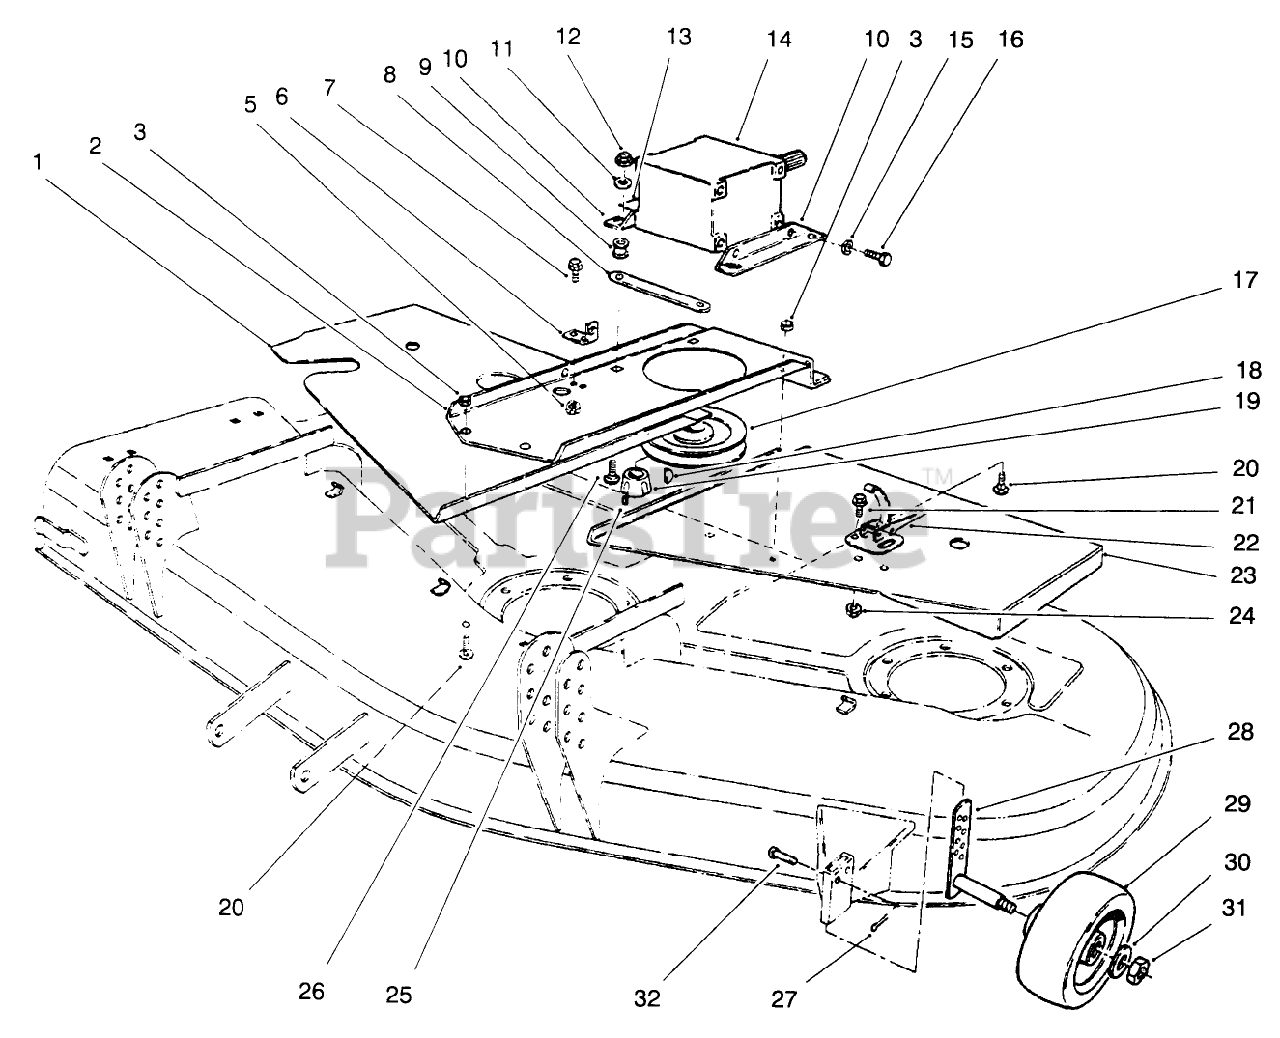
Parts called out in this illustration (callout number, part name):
1	Cover RH
2	Base-Gear Box
3	NUT-HHF, WHIZ
5	NUT-HF
6	Bracket-Extension
7	SCREW-HH
8	Cover-Gear Box
9	MOUNT
10	Bracket-Gearbox
11	WASHER
12	NUT-LOCK, SIDE
13	DECAL-OIL
14	Gearbox
15	WASHER-LOCK
16	SCREW-HH
17	PULLEY
18	KEY-WOODRUFF
19	Bushing-Taper Lock (Incl. Ref. #25)
20	SCREW-CARR
21	SCREW-HWH
22	CLAMP-SLOTTED
23	Cover LH
24	NUT-LOCK, FLANGE
25	SCREW-SET, HSH
26	SCREW-CARR
27	PIN-HAIR
28	GAGE-WHEEL
29	WHEEL-GAGE
30	WASHER-FLAT
31	NUT-LOCK, NI
32	PIN-CLEVIS
